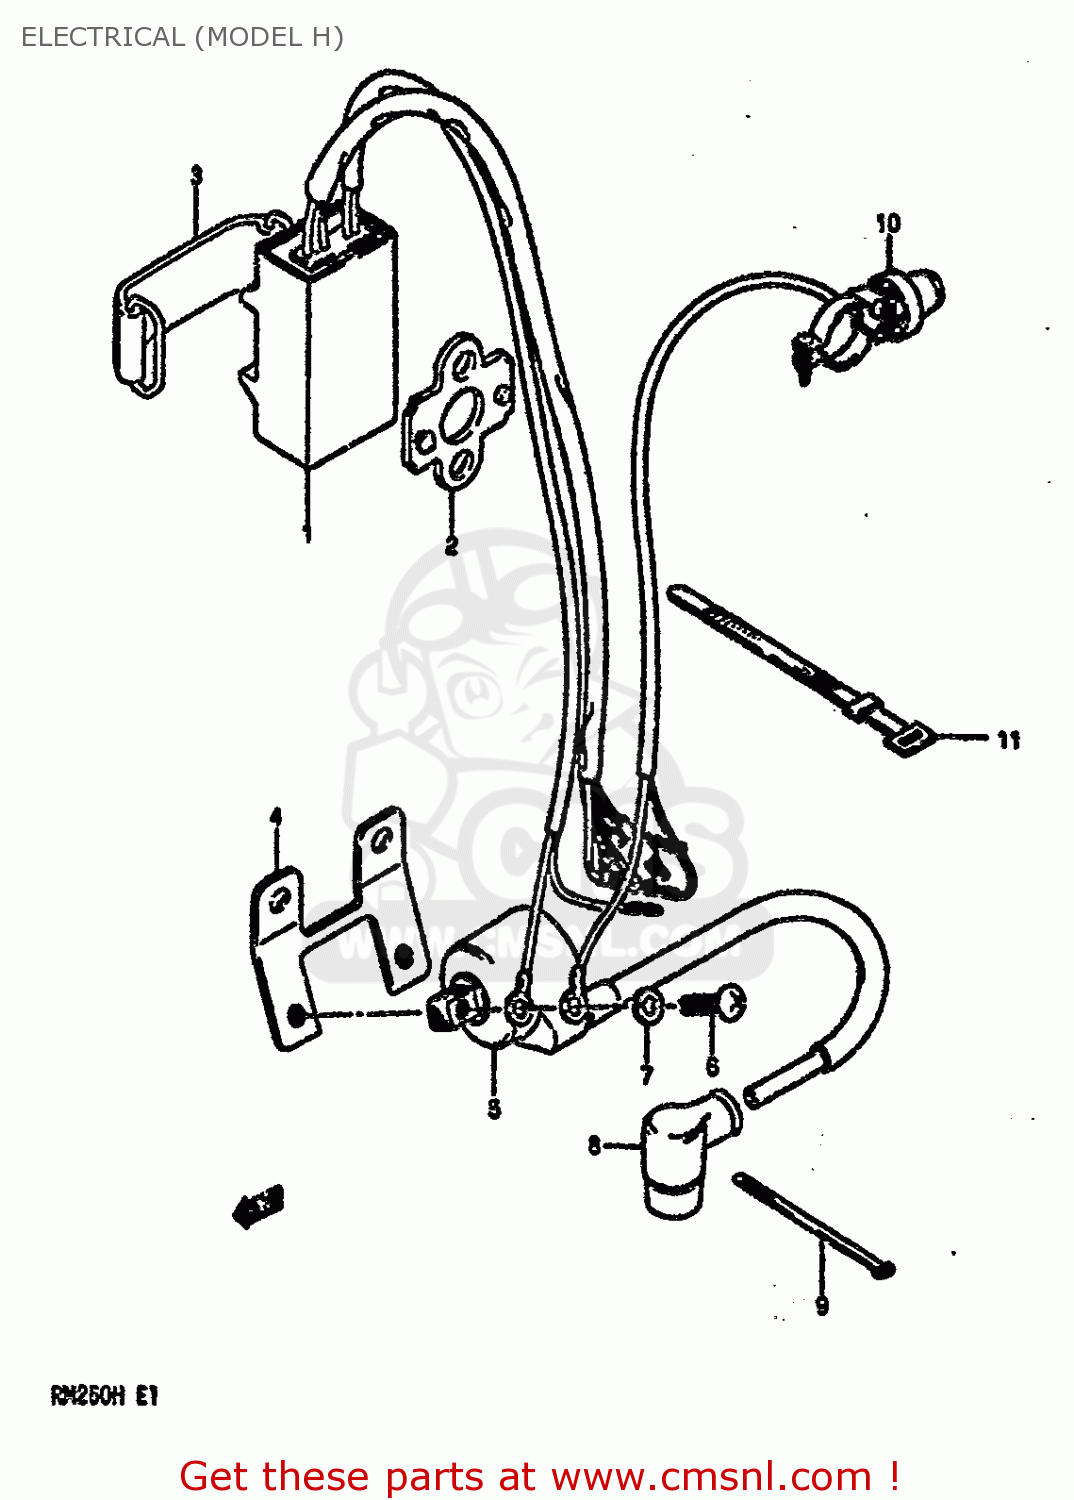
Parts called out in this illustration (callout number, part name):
1	UNIT,CDI
2	PROTECTOR,CDI UNIT
3	BAND
4	BRACKET,IGNITION COIL
5	COIL ASSEMBLY,IGNITION
6	SCREW
7	WASHER,LOCK
8	CAP,SPARK PLUG
9	CLAMP
10	SWITCH ASSEMBLY
11	CLAMP(L:120)
